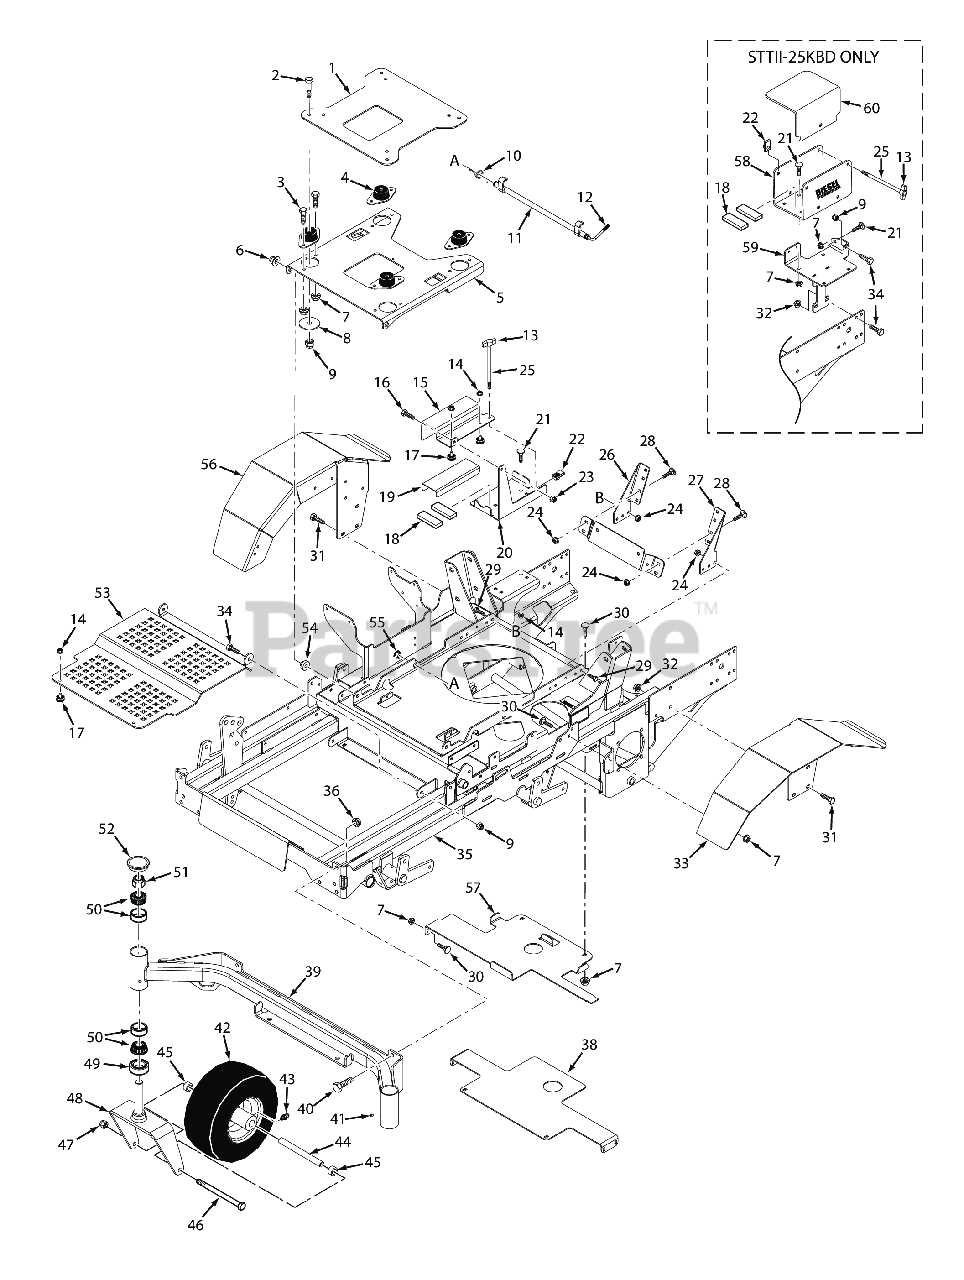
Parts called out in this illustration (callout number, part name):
1	Mounting Plate, Seat
2	Bolt, Hex Head 3/8-16 x 2-1/4" - 61"
3	BOLT, SERRATED FLANGE HEX HEAD 5/16-18 X 3/4"
4	Isolator, Seat
5	Seat Mounting Plate, Lower w/Decals
6	Nut, Flange Elastic Stop Nut, 3/8-16
7	Nut, Serrated Flange 5/16-18 (Right Front Engine Mounting, Briggs and Kohler Only)
8	Flatwasher, 3/8-.406 x 2.25" x .1875
9	HEX NUT, ELASTIC STOP LOCK, 3/8-16
10	Spring, Seat Latch
11	Lever Assy., Seat Release
12	Grip, Seat Latch
13	Knob, 1/4" Wing
14	Nut, Serrated Flange 5/16-18 (Right Front Engine Mounting, Briggs and Kohler Only)
15	Cover, Battery Box (Gas Only)
16	BOLT, SERRATED FLANGE HEX HEAD 5/16-18 X 3/4"
17	Bumper, Rubber 5/16-18 x 5/8"
18	PAD, BATTERY SUPPORT
19	Insulation, Battery Cover (Gas Only)
20	Battery Box (Gas Only)
21	Bolt, 5/16-18 x .75 RHSN Carriage
22	Bolt, Hex Head 3/8-16 x 1"
23	HEX NUT, ELASTIC STOP LOCK, 5/16-18
24	NUT, 1/4-20 SERRATED FLANGE HEX HEAD
25	Bolt, Hex Head 1/4-20 x 8"
26	Mounting Bracket - RH, Oil Cooler
27	Mounting Bracket - LH, Oil Cooler
28	Serr. Fl. Hex Head CPSCR, 1/4-20 x 3/4"
29	BOLT, SERRATED FLANGE HEX HEAD 5/16-18 X 3/4"
30	Bolt, 5/16-18 x .75 RHSN Carriage
31	Capscrew, 3/8-16 x 1.0" Serrated Flange Hex Hd
32	NUT, 3/8-16 SERRATED FLANGE HEX HEAD
33	FENDER WLMT, LH
34	Bolt, Hex Head, 3/8-16 x 1 Gr. 5
35	Mainframe Assy., w/Decals
36	Nut, 7/16-14 Flange Elastic Stop
37	Lockwasher, 7/16� Spring
38	Front Support, Fuel Tank
39	Caster Support Weldment - 52V
39	Caster Support Weldment - 61V
39	Caster Support Weldment - 72V
40	BOLT, HEX HEAD, 7/16-14 X 1-1/4
41	Plug, 1/4-28 THD Form
42	Wheel Assy, 61V, 72V (Incl. 20, 54, 55)
42	Bearing, Tapered Roller
42	Roller Bearing, Short
43	Fitting, Grease
44	Sleeve, Caster Wheel (61V, 72A/VS)
45	Spacer, Caster Wheel
46	Bolt, Hex Head 1/2-13 x 9-1/2" (61V & 72A/VS)
47	HEX LOCKNUT, ELASTIC STOP, 1/2-13
48	Yoke Weldment, Caster (61V & 72A/VS)
49	Seal, 2.00" O.D. x 1.625" Bore
50	BEARING & CUP, TAPERED SPINDLE
51	Nut, Hex Elastic Stop 1.0"-14
52	Cap, Grease
53	Foot Plate
54	Sleeve, Seat Base Mounting
55	RETAINING RING, 5/8" EXTERNAL "E"
56	Fender, RH
57	Rear Support, Fuel Tank
58	Battery Box w/Decal (Diesel Only)
59	Battery Bracket Weldment (Diesel Only)
60	Cover, Battery (Diesel Only)
60	Insulation, Battery Cover
